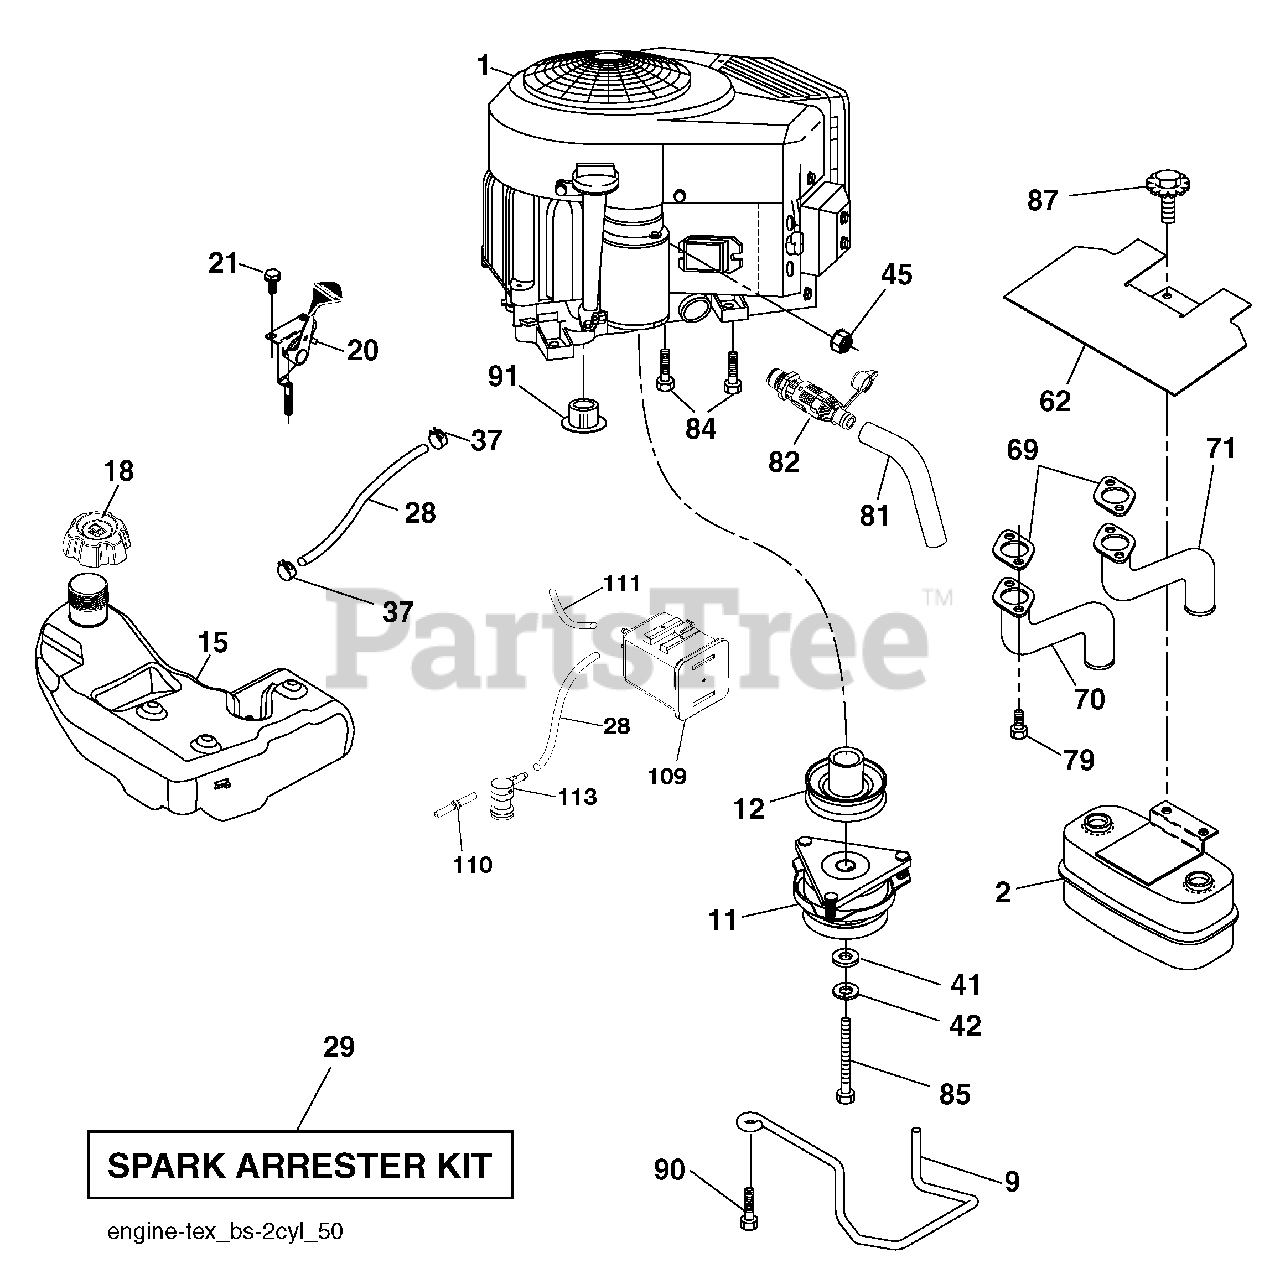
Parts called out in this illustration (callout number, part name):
9	Keeper Belt Engine
11	Clutch Electric
12	Pulley Engine
15	Tank Fuel 4.0
18	Cap Asm
20	Control Throttle
21	Screw #10 x 0.750
28	Fuel Line
29	Spark Arrester Kit
37	Clamp Hose
41	Washer 1-1/2 OD x 15/32 ID x .250
42	Washer Lock 7/16
45	Nut Keps Hex 1/4-20 unc
62	Shield Heat Muffler
70	Tube Exhaust LH
71	Tube Exhaust RH
79	Screw Socket Head 5/16-18 x 1
81	Tube Drain Oil Easy
82	Valve Oil Drain
84	Screw 3/8-16 x 1-1/4
85	Bolt Hex 7/16-20 x 4 x Gr. 5-1.5
87	Bolt 5/16-18 x 3/4 w/Sems
90	Screw 3/8-16 x 1
109	Canister Carbon Filter Asm
110	Valve Anti Slosh
111	Purge Line
113	Valve Slant Cartrdg
